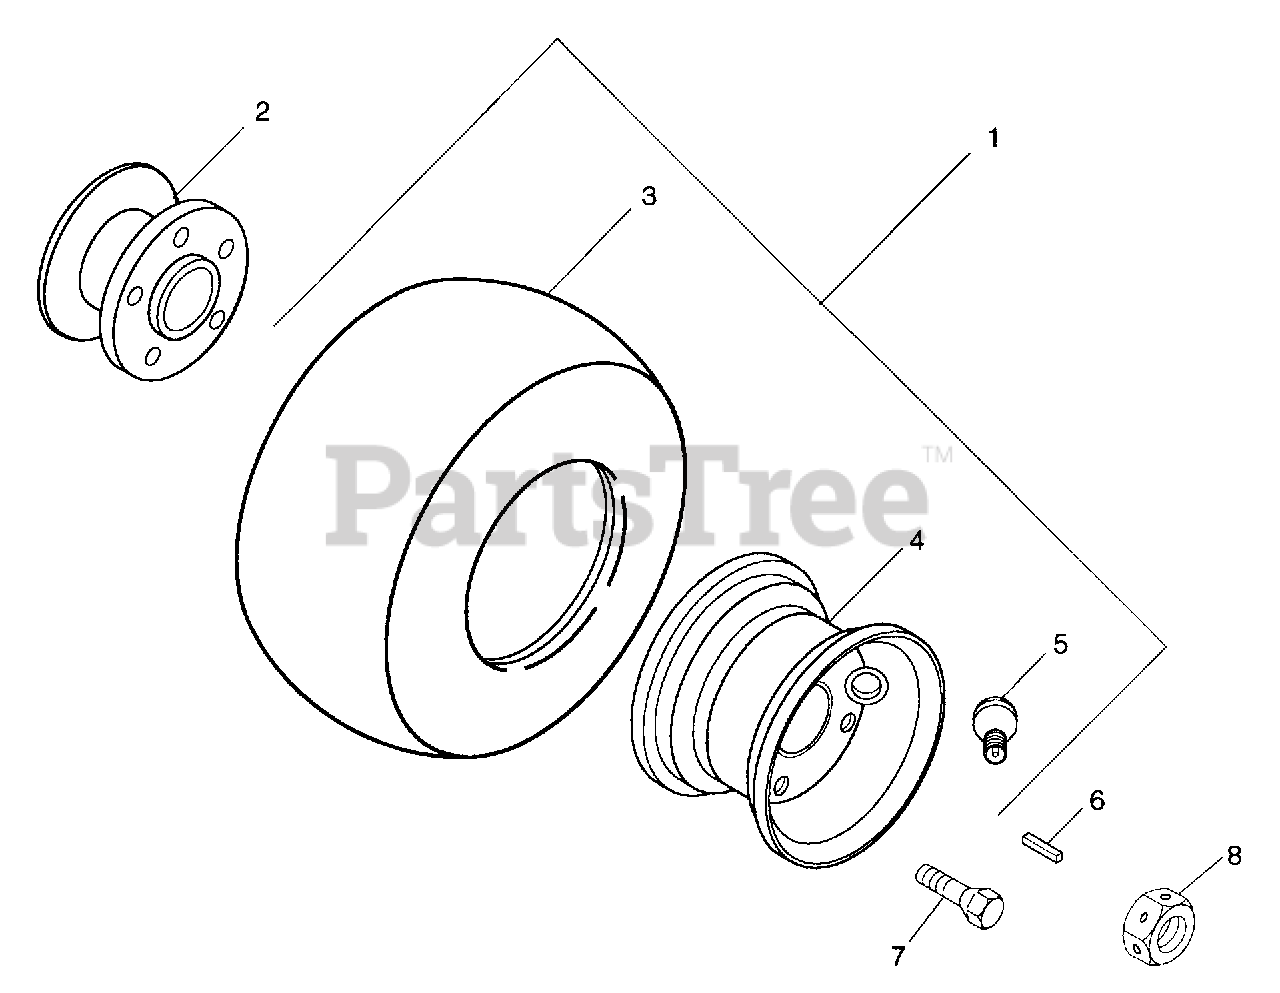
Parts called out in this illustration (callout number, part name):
1	Tire/Wheel Assembly 20 x 10-10
2	Hub, Disc Brake
3	Tire 20 x 10.00-10 Turf Trac RS
4	Wheel, 10.00 x 7.75
5	Valve Stem Assembly
6	Key, Rectifier .313 x .275 x .932
7	Bolt .44-20 x 1.0
8	Nut-Pack 1.00-20
